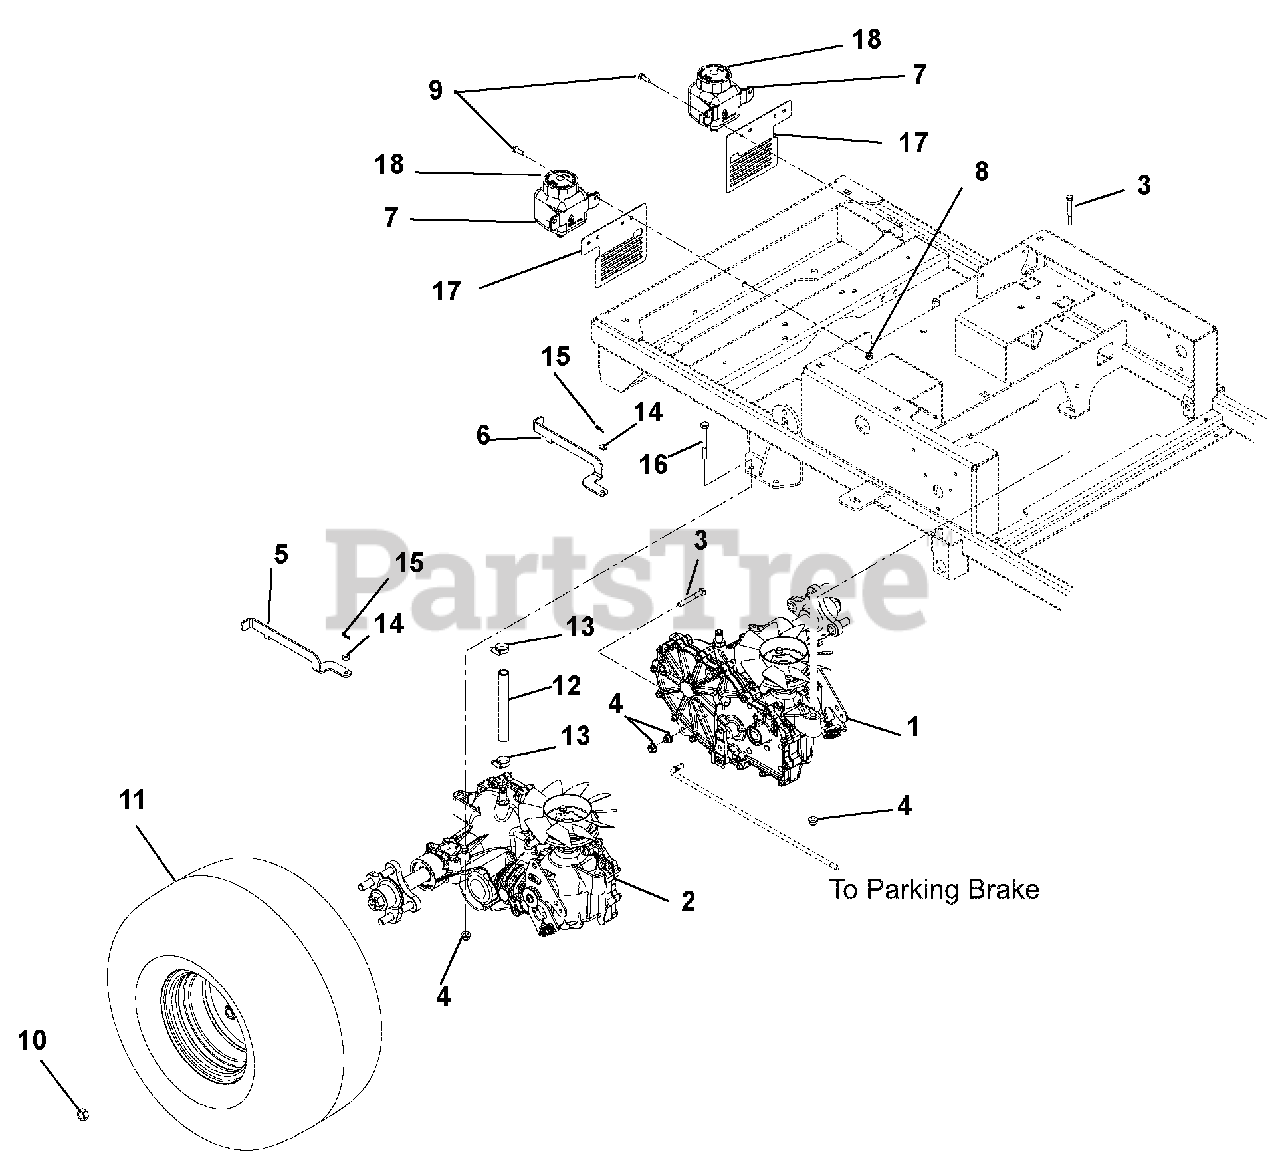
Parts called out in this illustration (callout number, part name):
1	Transaxle, ZT2800 Left Hand
2	Transaxle, ZT2800 Right Hand
3	Bolt, Hex .31-18 x 2.25 Grade 5
4	Nut 5/16-18 Flange Nyloc
5	Dump Valve, Right Hand
6	Dump Valve, Left Hand
7	Tank, Expansion ZT2800
8	Nut, Locking Top Flange .25-20
9	Bolt, Hex .25-20 x .75 Grade 5
10	Nut, Wheel .50-20 13/16
11	Tire/Wheel Assembly, 20 x 8.0-8
12	Hose, Oil Reservior
13	Clamp, .88 Diameter Hose
14	Washer, Flat Steel .265 x .50 x .087
15	Pin, Hair Internal .06 x .18 x .77
16	Bolt, Hex .31-18 x 2.75
17	Bracket, Rear Fan Guard
18	Cap, Hydro Reservoir Replacement
